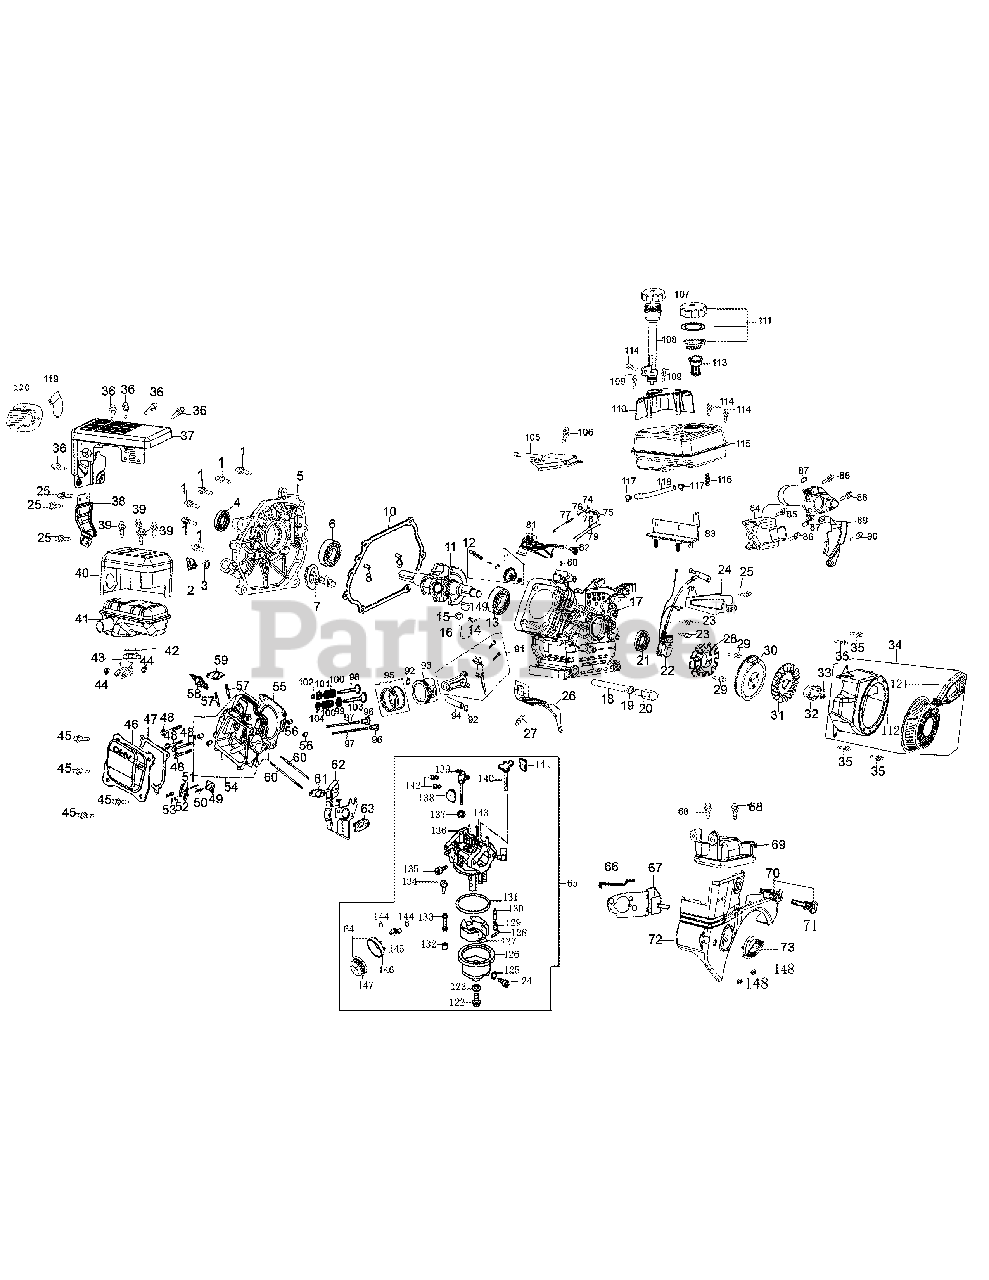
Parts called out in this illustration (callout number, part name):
2	Valve Cover
3	Breather Hose
4	Hose Clamp
5	Head Cover Gasket
6	Intake Valve Spring Seat
7	Pivot Locking Nut
8	Valve Adjusting Nut
9	Rocker Arm
10	Pivot Bolt
11	Exhaust Valve Adjuster
12	Exhaust Valve Spring Seat
13	Valve Spring
14	Intake Valve Seal
16	Push Rod Guide Plate
17	Cylinder Head - Complete
18	Spark Plug
19	Muffler Assembly
20	Stud
21	Muffler Gasket
24	Exhaust Pipe Shield
27	Muffler Shroud
28	Stud, M6 x117
29	Stud, M6 x 105
30	Carburetor Insulator Gasket
31	Carburetor Insulator Plate
32	Carburetor Gasket
33	Carburetor Assembly
34	Carburetor Gasket Plate
35	Choke Control Bracket
36	Engine Shroud
38	Choke Knob
39	Throttle Control Knob
40	Ignition Switch
43	Choke Push Rod
44	Heater Box
46	Cylinder Head Gasket
47	Push Rod Kit (incl. intake and exhaust rod)
48	Tappet
49	Dowel Pin
52	Piston Ring Set
53	Piston Pin Snap Ring
54	Piston
55	Piston Pin
56	Oil FIll Plug Assembly
57	Air Shield
58	Connecting Rod Assembly
59	Governor Arm Shaft
60	Washer
61	Governor Seal
62	Cotter Pin
63	Camshaft Assembly
64	Radial Ball Bearing
65	Flywheel Key
66	Crankshaft Assembly
67	Governor Gear/Shaft Assembly
68	Dowel Pin, 7 x 14
69	Dowel Pin, 9 x 14
70	Crankcase Cover Gasket
71	Case Cover
71	Cover Complete, Left Crankcase
72	Cover Bolt
73	O-Ring
74	Oil FIll Plug
74	Oil Fill Plug
75	Oil Seal
76	Crankcase
77	Oil Drain Pipe
78	Washer
79	Oil Drain Plug Washer
80	Oil Seal
81	Ignition Coil
82	Air Flow Shield
83	Fuel Line Kit (incl. clamps and fuel line)
84	Hose Clamp
85	Oil Drain Assembly, includes 77, 78, 79
86	Flywheel
87	Cooling Fan
88	Starter Cup
89	Nut
90	Valve Kit (incl. intake and exhaust valve)
90	Valve Kit
92	Blower Housing
93	Washer
95	Recoil Starter Assembly
96	Ignition Key
97	Throttle Control Assembly
99	Governor Shield
100	Governor Spring
101	Throttle Return Spring
102	Governor Rod
104	Nut
109	Engine/Dipstick Cover
113	Dipstick Tube
115	Dipstick
117	Fuel Cap Assembly
118	Fuel Level Indicator
119	Fuel Tank
121	Switch Housing MTG Bracket
122	O-Ring
123	Bolt, M4 x 55
124	Bolt, M4 x 60
126	Dowel Pin
127	Electric Starter
129	Blower Housing Shield
130	Primer
131	Bolt
132	Drain Bolt
133	Gasket, Throttle Plate
134	Float Pin
135	Emulsion Tube
136	Needle Valve
137	Main Jet
138	Needle Valve Spring
139	Float
140	Fuel Bowl Gasket
141	Fuel Drain Plug Gasket
142	Fuel Bowl Gasket
143	Wire Clip
145	Muffler Stud Assembly
146	Choke Shaft
147	Choke Plate
148	Throttle Shaft
149	Throttle Plate
150	Screw, M3×5
151	Lock Washer
152	Idle Jet Assembly
153	Idle Speed Adjusting Screw
154	Fuel Bowl
155	Governor Arm Bracket
155	Hose Clamp
156	O-Ring
